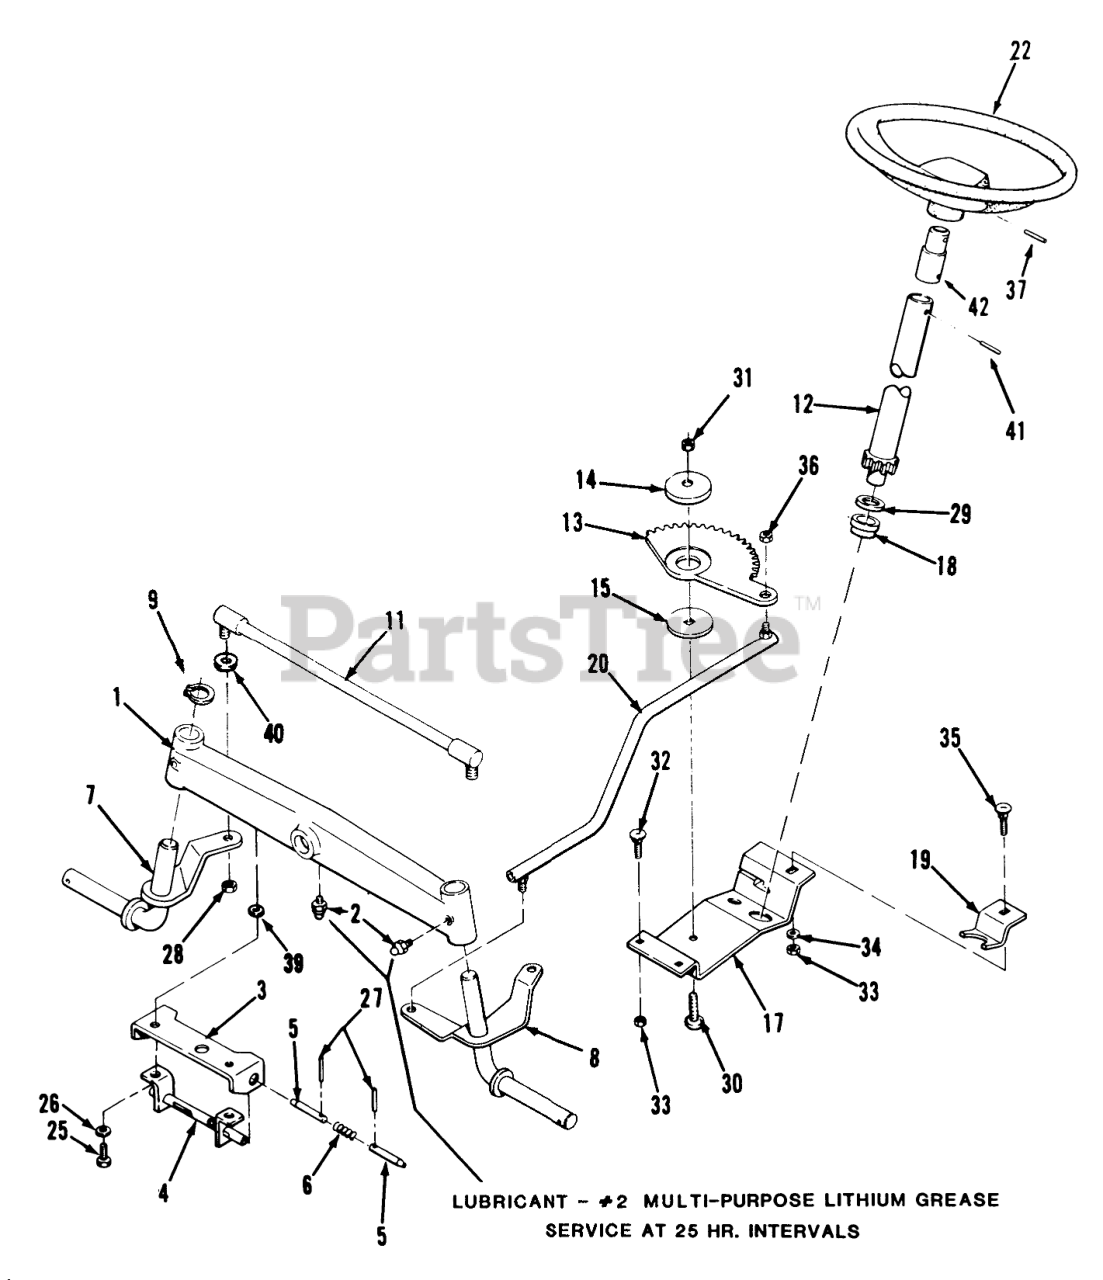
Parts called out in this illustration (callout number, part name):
1	AXLE-FRONT R
2	FITTING-GREASE
3	BRACKET-SUPPORT R
4	TUBE & BRACKET ASM R
6	SPRING
7	ASSY ARM STEERING R
8	ASSY ARM STEERING R
9	RING-RETAINING
11	ASS'Y-TIE ROD R
12	ASSY PINION & SHA B
13	GEAR SECTOR
14	BUSHING
15	WASHER-BEARING
17	BRKT-STEERING GEA R
18	BEARING-WHEEL
19	RETAINER R (NS)
20	ASSY BALL JOINT L R
22	STR'G-WHL 13" TORO
25	SCREW-HH
26	WASHER-LOCK
27	PIN-SPRING
28	Nut-Lock
29	SHIM-WASHER
30	SCREW-CARR
32	BOLT-CARR
33	NUT-LOCK, NI
34	WASHER-PLAIN
35	BOLT-CARR
36	NUT-6
37	SPIROL PIN 5/16X13/8
39	WASHER
40	WASHER-SPECIAL
41	PIN-ROLL
42	SHAFT-COUPLER
